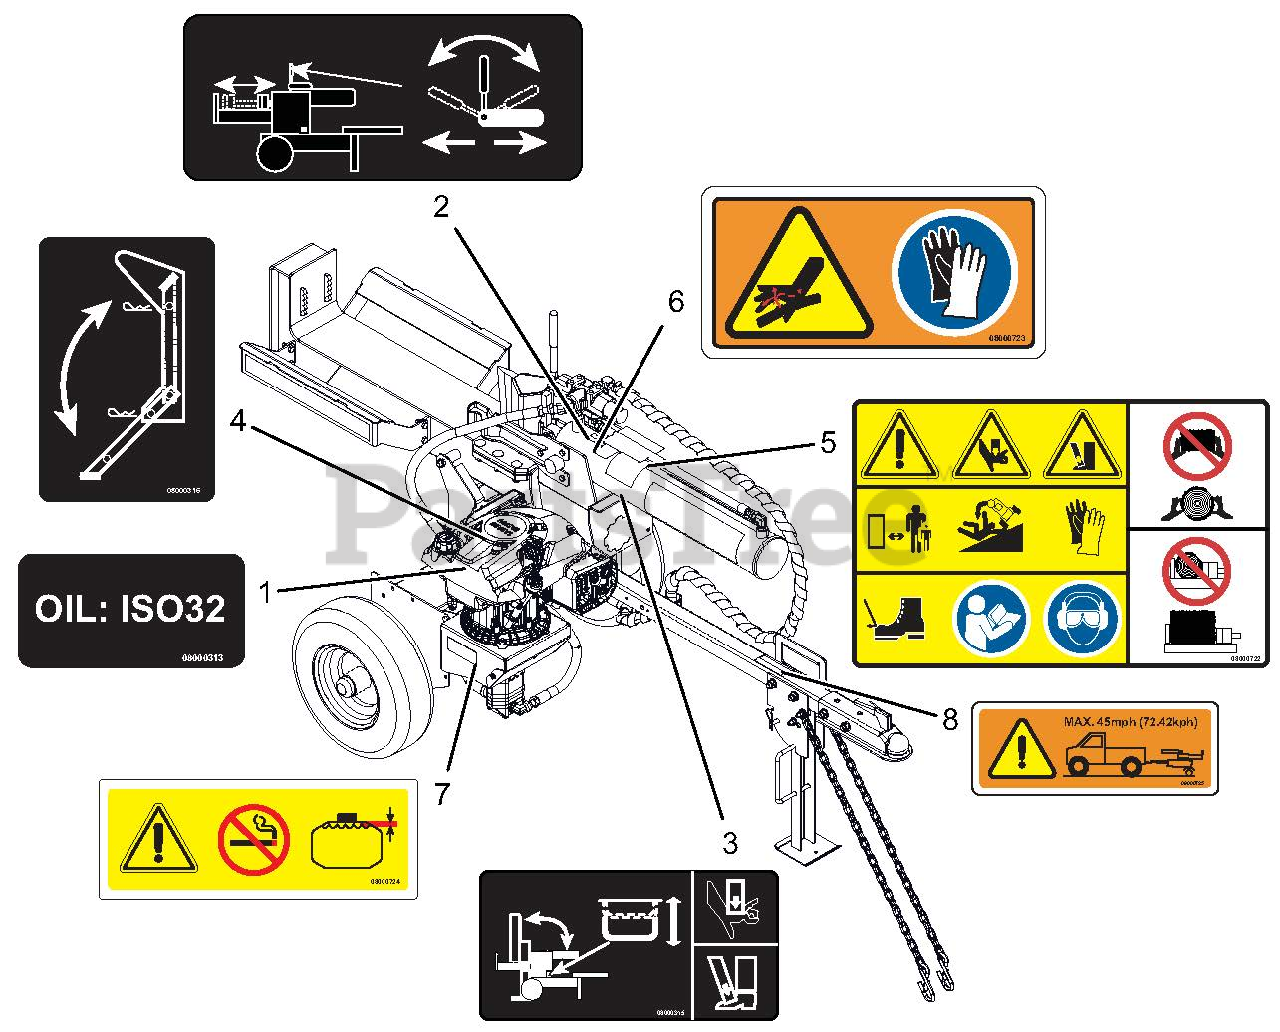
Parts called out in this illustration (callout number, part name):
1	DECAL, LOG SPLITTER-HYD OIL
2	DECAL, LOG SPLITTER-RAM OP
3	DECAL, LOG SPLITTER-TILT OP
4	DECAL, LOG SPLITTER-REAR STAND
5	DECAL,DANGER LOG SPLITTER
6	DECAL,HYD WARNING
7	DECAL,FUEL WARNING
8	DECAL,TOWING
